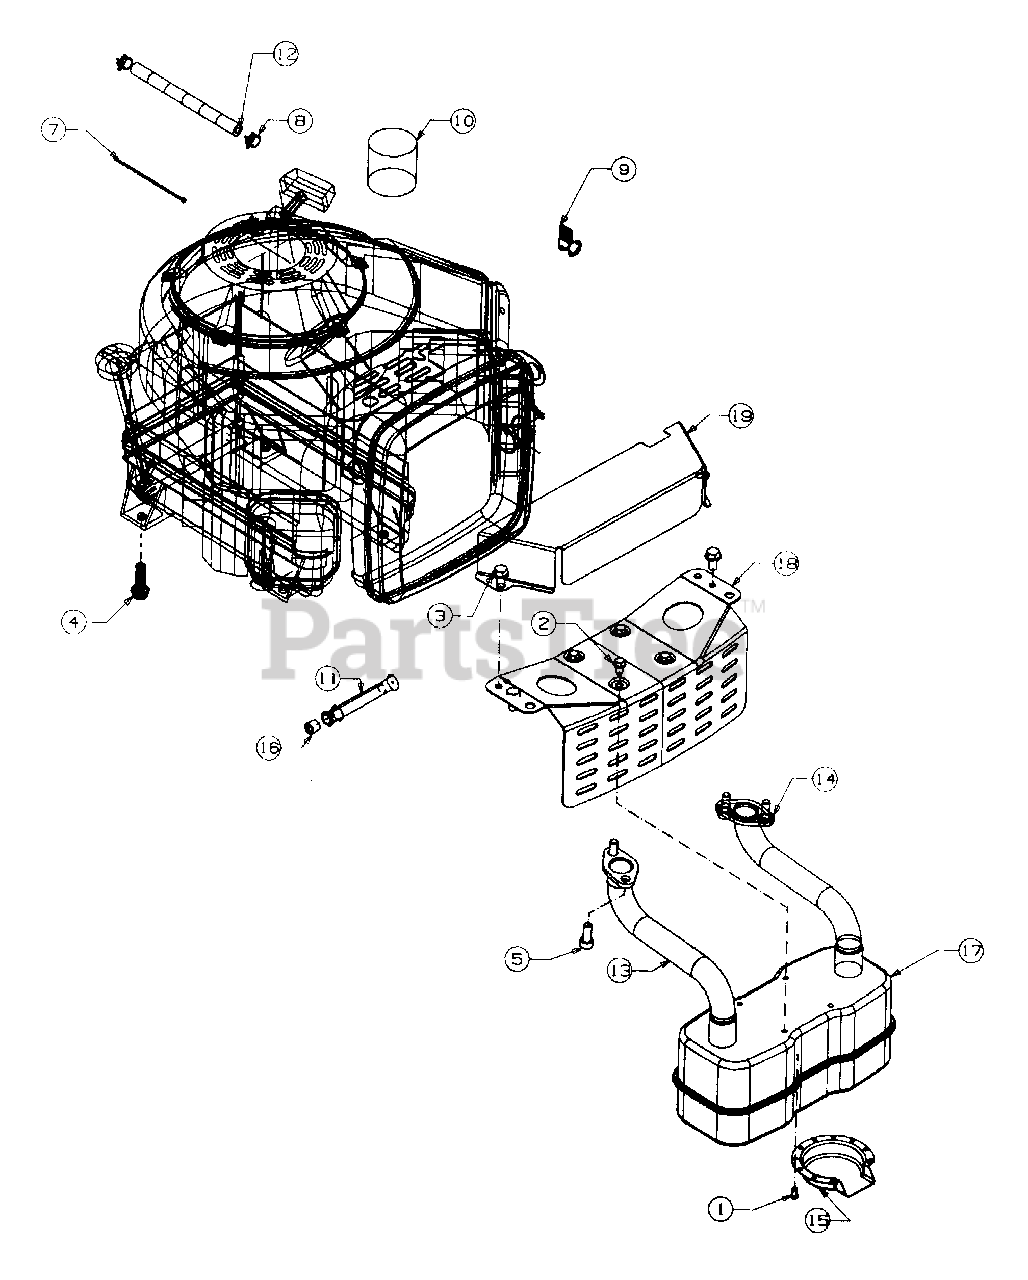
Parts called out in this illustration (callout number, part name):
1	Hex Tap Scr. #8-32 x .38" Lg.
2	Hex Wash. TT-Tap Scr. 1/4-20 x .5" Lg.
3	Hex Wash. TT-Tap Scr. 5/16-18 x .62" Lg.
4	Hex Wash. TT-Tap Scr. 3/8-16 x 1.25" Lg.
5	Socket Hd. Scr. M8 x 1.25" Lg.
11	Pipe Nipple 3/8 x 3.8" Lg.
12	Fuel Line
13	Exhaust Tube - R.H.
14	Exhaust Tube - L.H.
15	Deflector
16	Hex Pipe Plug
17	Muffler
18	Muffler Bracket
